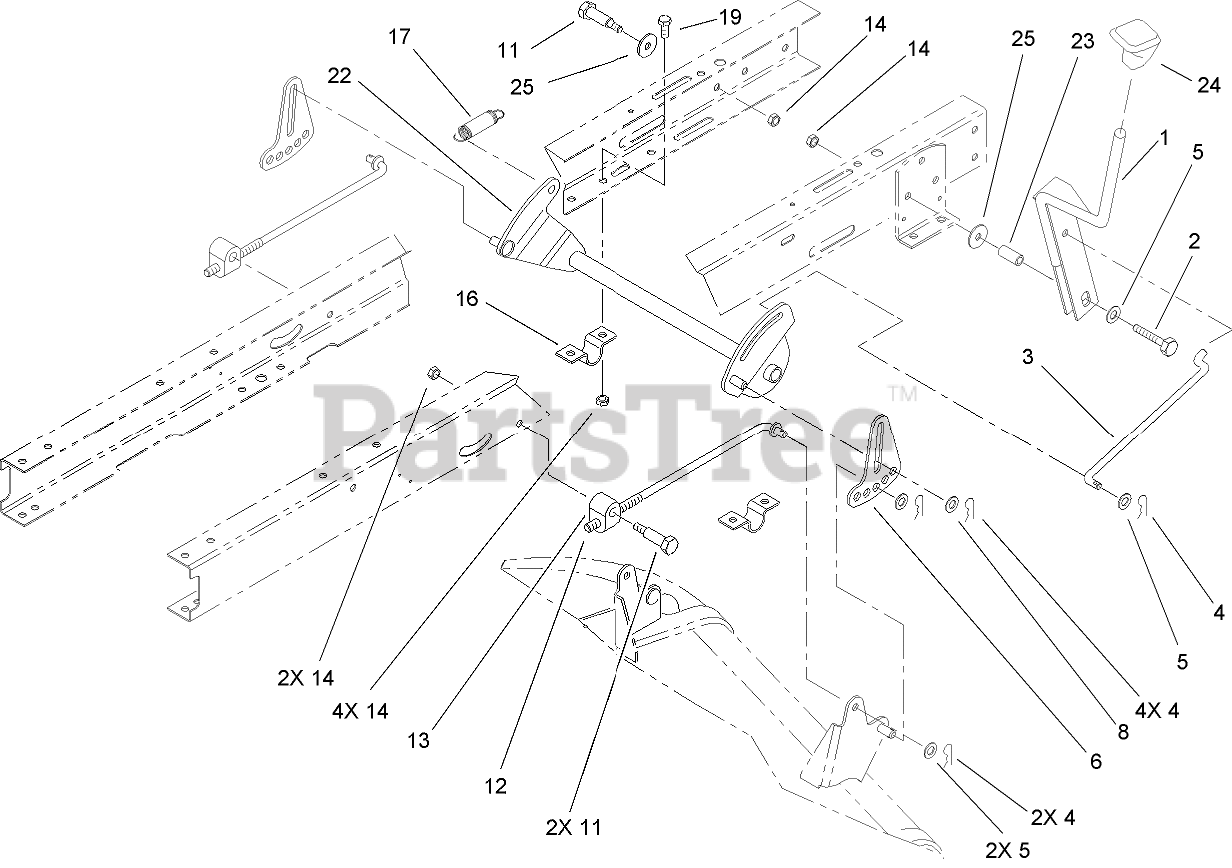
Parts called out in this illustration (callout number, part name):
1	HOC LEVER ASM
2	SCREW-HH
3	LINK-HOC
4	PIN-COTTER
5	WASHER-FLAT
6	LINK-ADJUSTING, HOC
8	WASHER-HARDENED
11	SCREW-SHOULDER, HH
12	ROD-HANGER, REAR
13	TRUNNION-HOC
14	NUT-LOCK, NI
16	CLAMP-PIVOT, HOC
17	SPRING-EXTENSION
19	SCREW-HH
22	PIVOT ASM
23	SPACER
24	KNOB-SHIFT
25	WASHER-PIVOT
